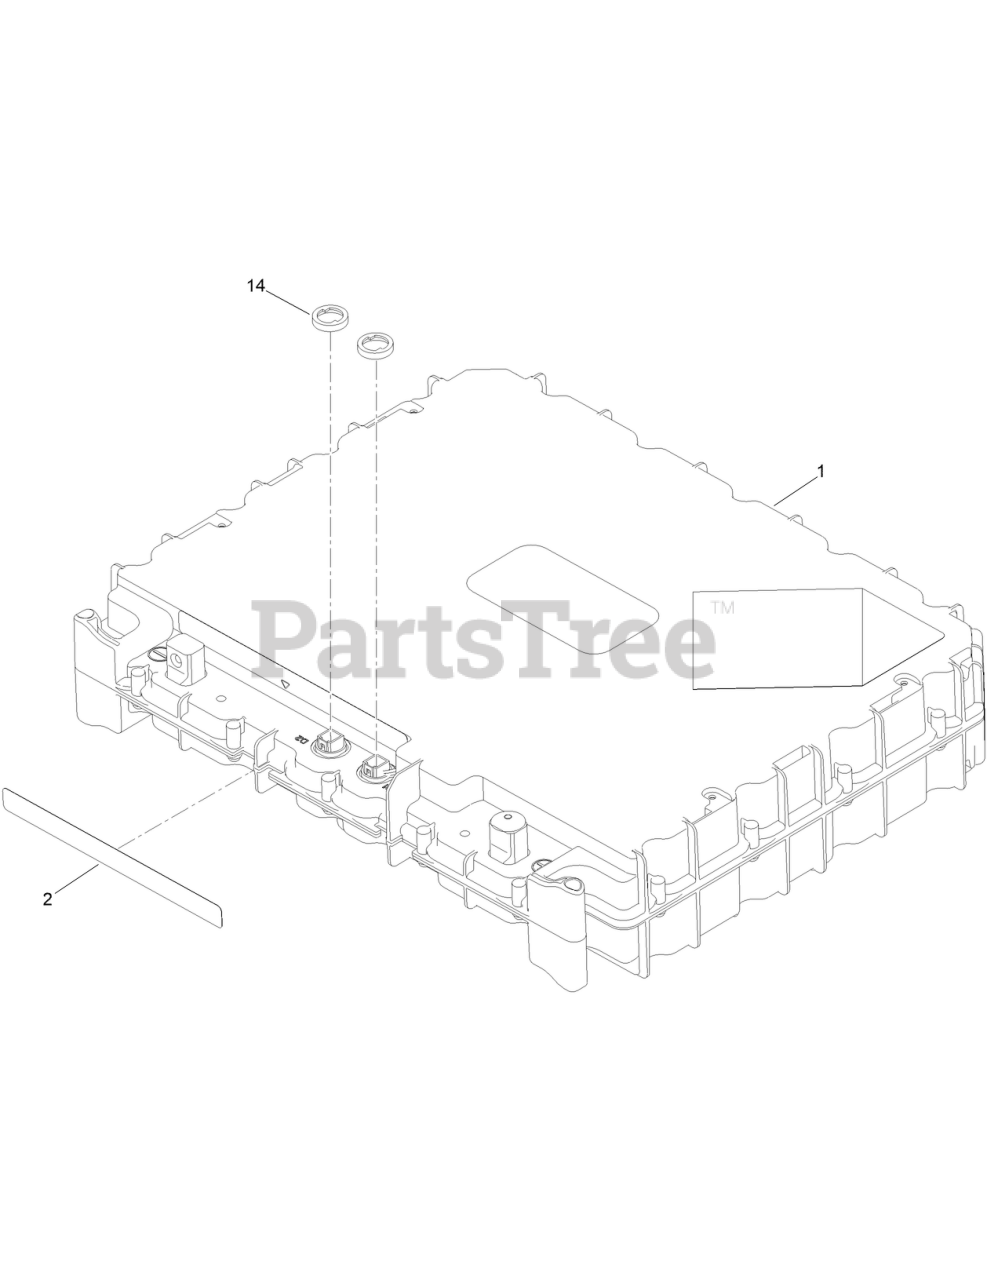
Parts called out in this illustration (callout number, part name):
1	BATTERY ASM
2	DECAL-WARNING, BATTERY
14	NUT-MOUNTING, JWPF PANEL LOCK
